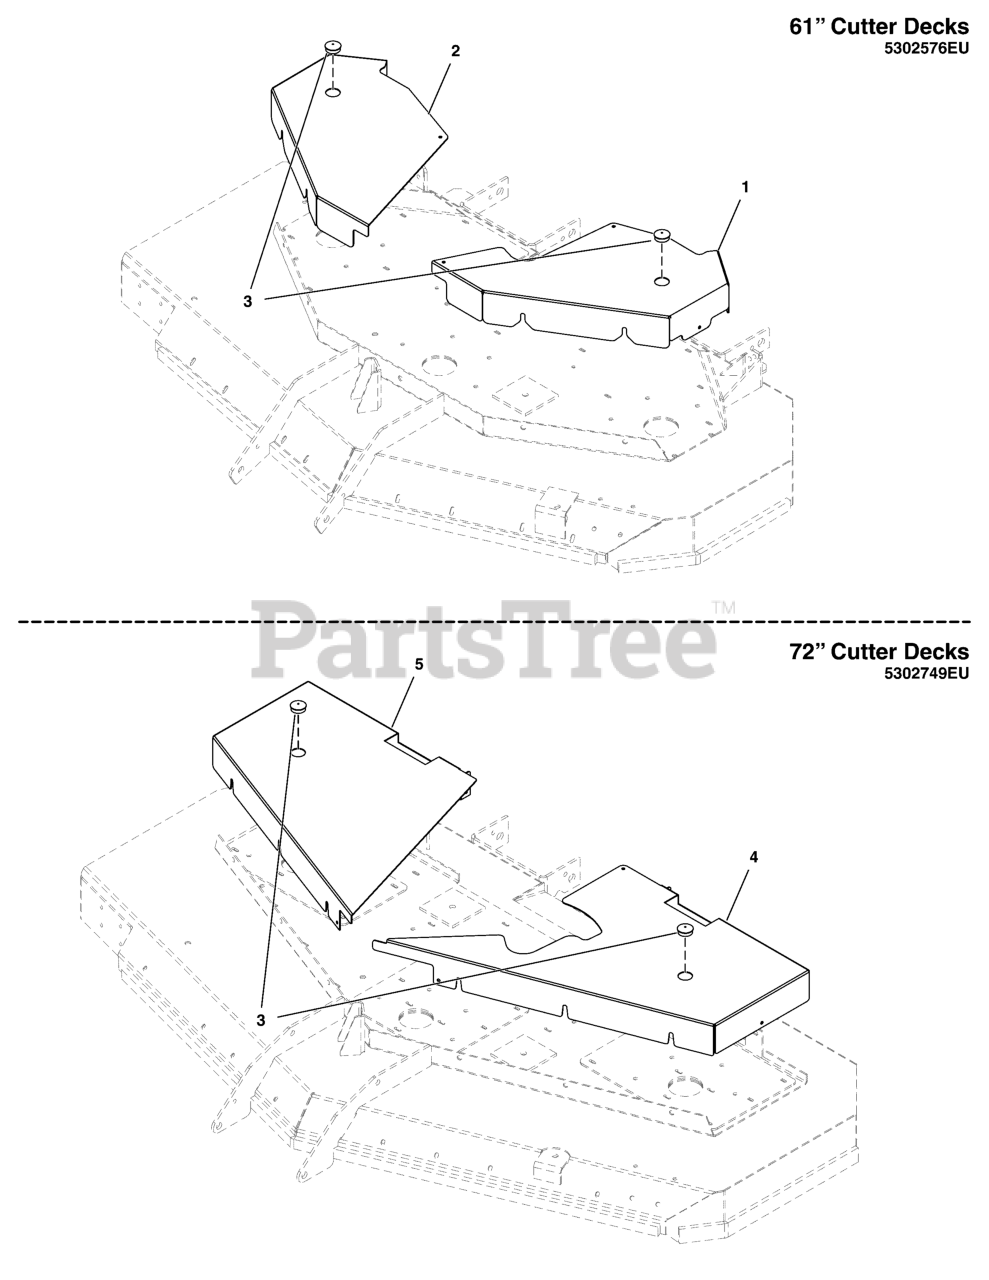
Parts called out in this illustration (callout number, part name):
1	PLATE, DECK GUARD, LH - 61 - RED
2	PLATE, DECK GUARD, RH - 61 - RED
3	PLUG, PANEL, 1.25 - BLACK
4	PLATE, DECK GUARD, LH - 72 - RED
5	PLATE, DECK GUARD, RH - 72 - RED
